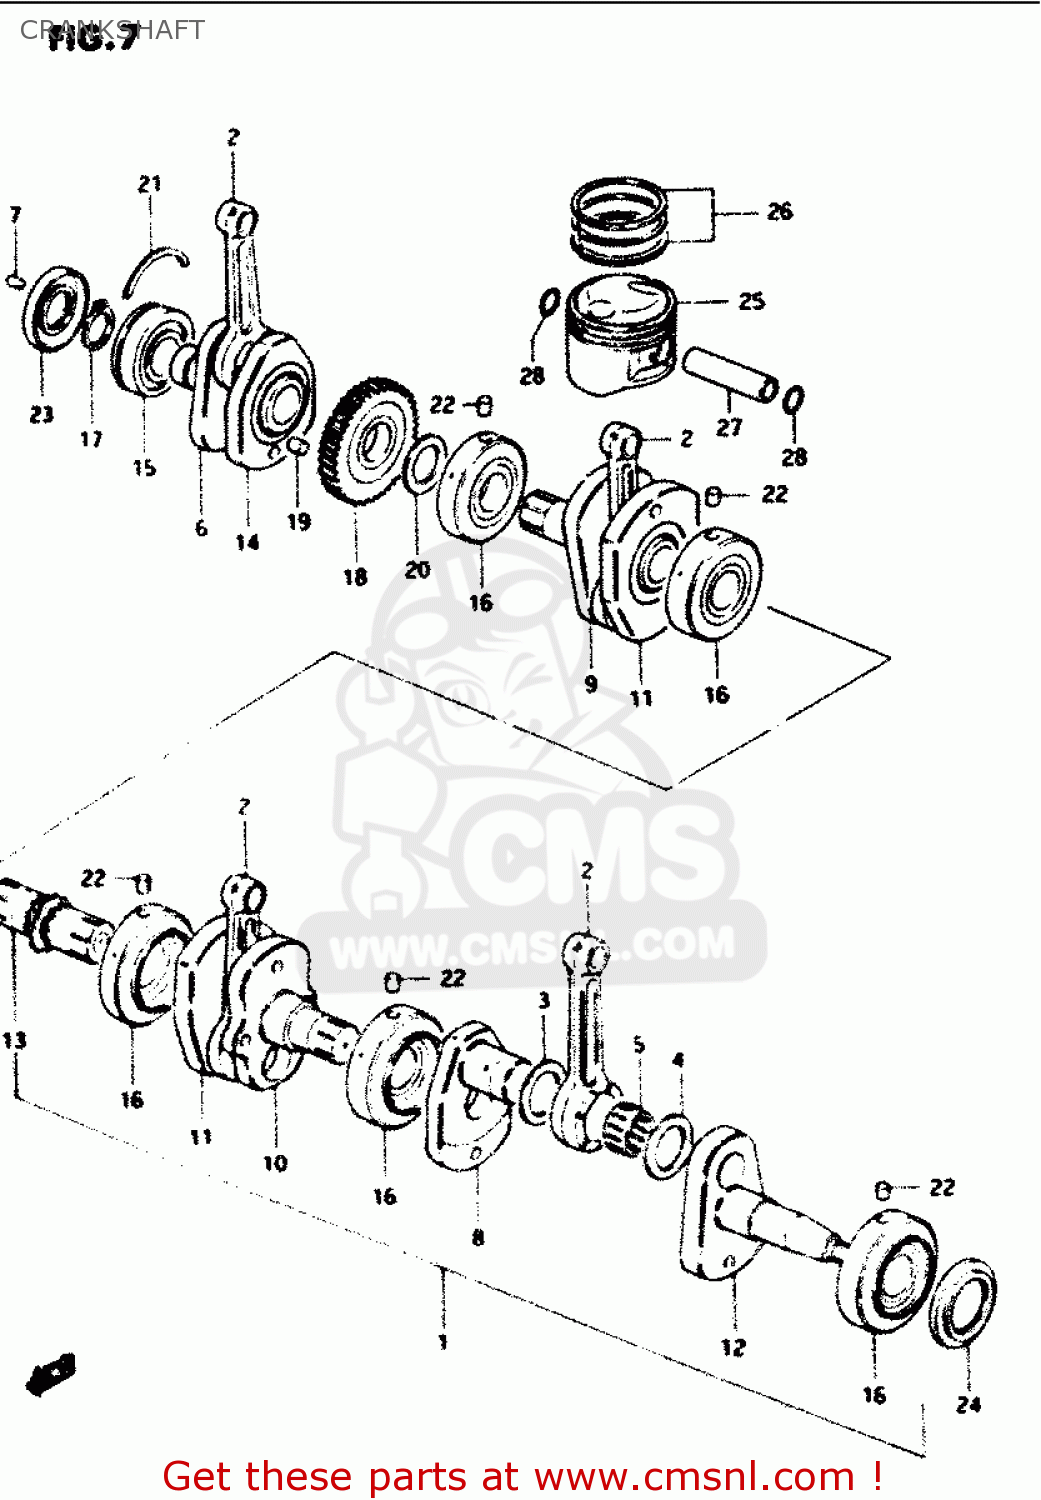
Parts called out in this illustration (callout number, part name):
1	CRANKSHAFT ASSEMBLY
2	ROD,CONNECTING
3	WASHER(31X48.5X1)
4	WASHER(31X48.5X2)
5	BEARING
6	CRANKSHAFT,RIGHT
7	PIN
8	WEB,CRANK
9	CRANKSHAFT,MIDDLE,RIGHT
10	CRANKSHAFT,MIDDLE,LEFT
11	WEB,CRANK,MIDDLE
12	CRANKSHAFT,LEFT
13	SHAFT,TIMING CHAIN DRIVE
14	WEB,CRANK,RIGHT
15	BEARING(30X72X19)
16	BEARING(32X72X21)
17	CIRCLIP,30MM
18	GEAR,PRIMARY DRIVE
19	PIN
20	WASHER
21	C RING
22	PIN
23	SEAL,OIL(30X72X11)
24	SEAL,OIL(47.3X60X6.5)
25	PISTON
26	RING SET,PISTON
27	PIN,PISTON
28	CIRCLIP,PISTON PIN
